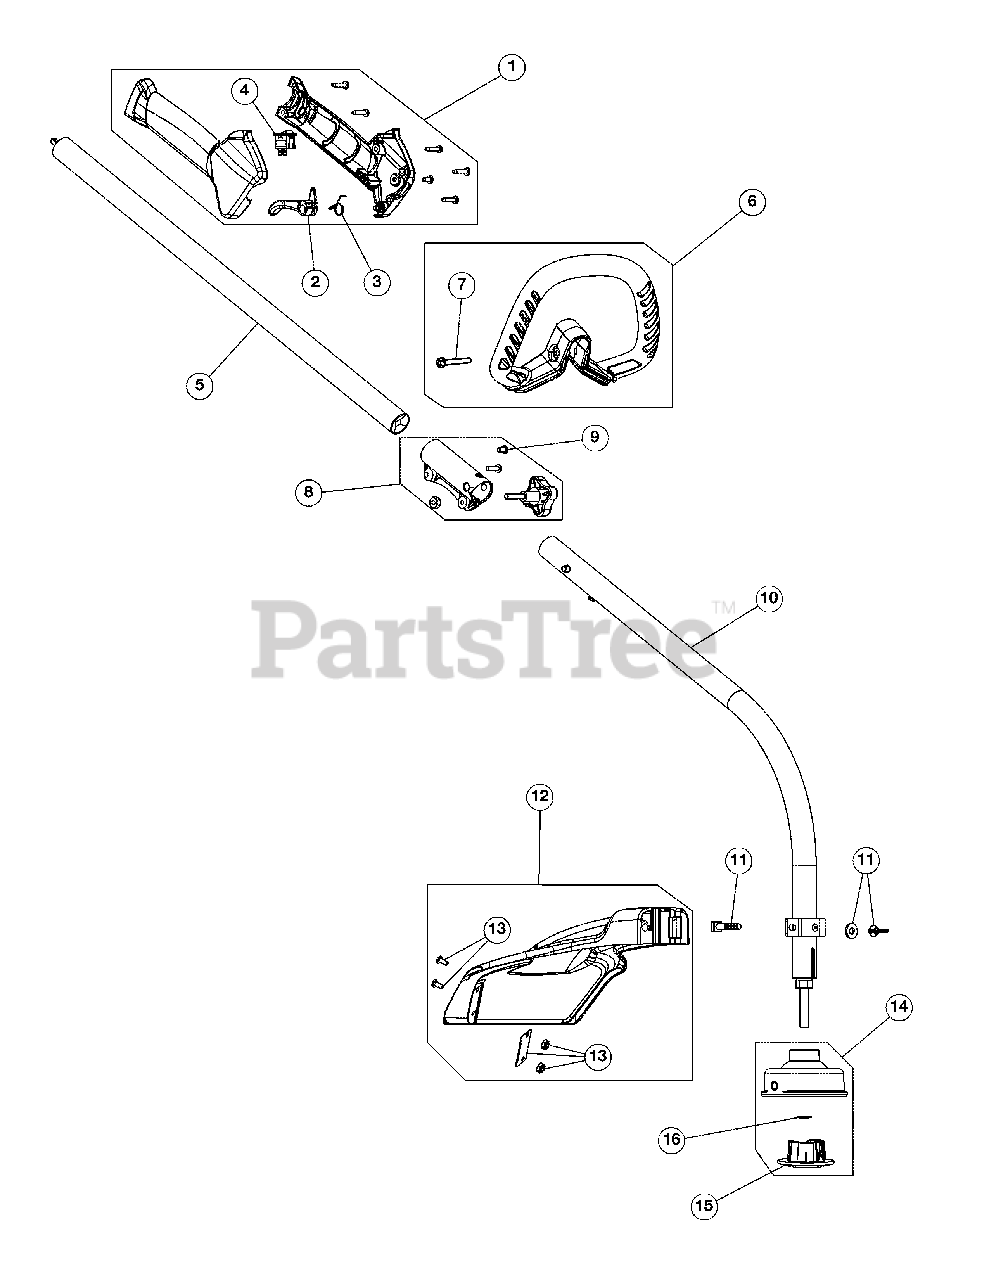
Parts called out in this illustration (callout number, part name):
1	Throttle Housing Assembly (Incl. 2-4)
2	Throttle Trigger
3	Throttle Trigger Spring
4	Switch Assembly
5	Upper Drive Shaft Assembly
6	D-Handle Assembly (Incl. 7)
8	Split Boom Coupler (Incl. 9)
9	Coupler Anti-Rotation Screw
10	Lower Drive Shaft Housing
11	Shield Mount Hardware
12	Shield Assembly (Incl. 13)
13	Blade Assembly
14	Cutting Head Assembly (Incl. 15 & 16)
15	Cutting Head Cap
16	Push Nut
